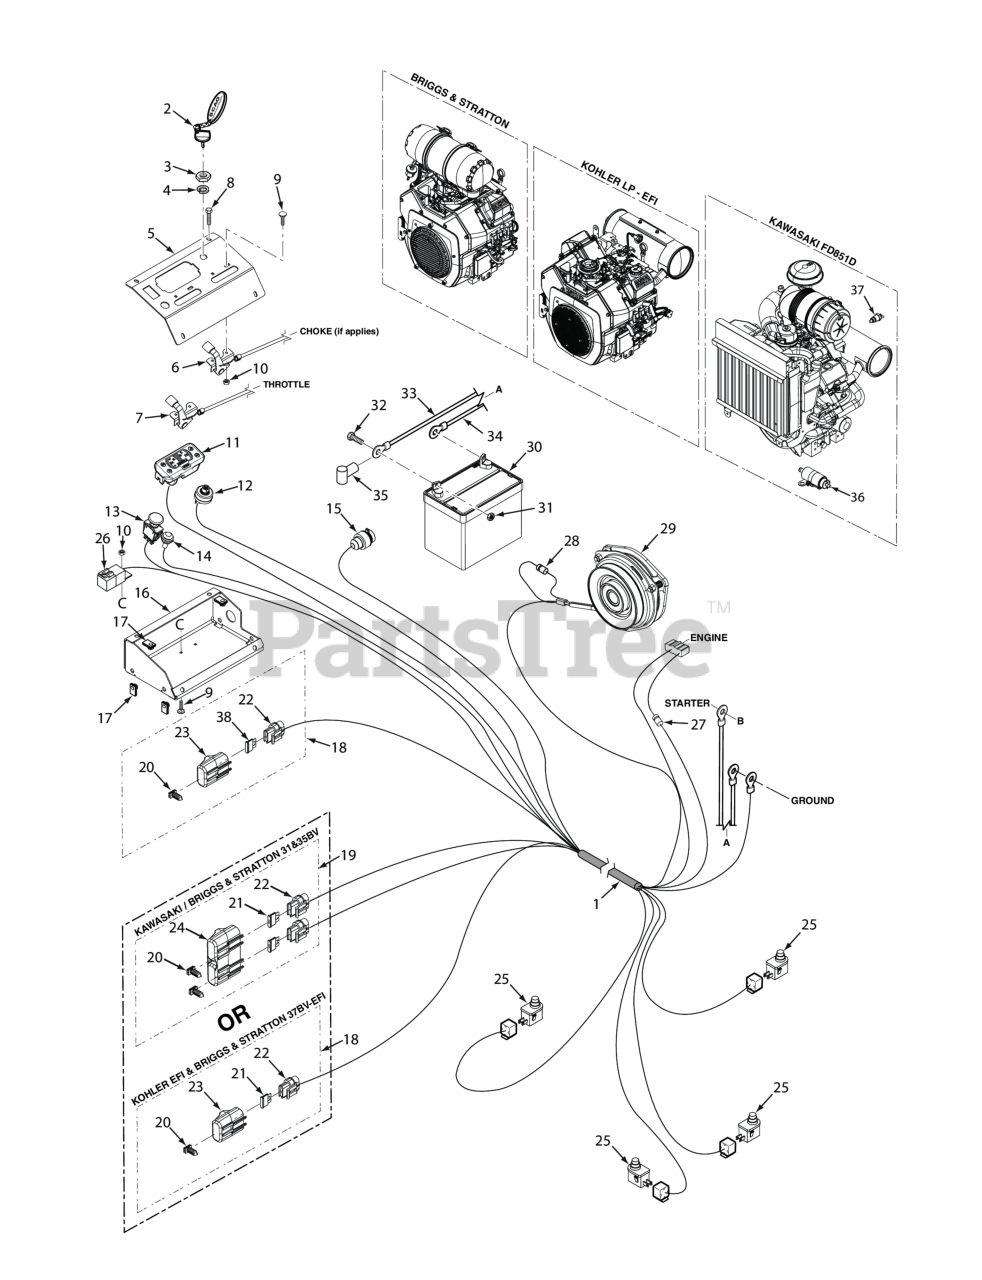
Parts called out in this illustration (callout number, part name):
1	Wire Harness, STTII-BV-EFI (Briggs & Stratton)
2	Key, Assembly w/Fob
3	Nut, 5/8-32 Special
4	LOCK WASHER, 5/8" INTERNAL TOOTH
5	Instrument Panel w/Decal
6	Control Cable (Kawasaki FX921 Throttle & Choke Cable)
7	Control Cable (Briggs & Stratton)
8	Bolt, Hex Head Serrated Flange 1/4-20 x 3/4"
9	Bolt, Carriage #10-24 x 1/2"
10	Nut, Elastic Stop #10-24
11	Tiger Eye, Cluster Gauge
12	KEY SWITCH(INCLUDES MOUNTING HARDWARE)
13	Switch, PTO - 10 Amp
14	Indicator Light, Glow Plugs (Includes Mounting Hardware)
15	Power Plug, 12V
16	Base, Instrument Panel
17	Bolt, Hex Head 3/8-16 x 1"
18	Single Fuse Assy., Excluding Fuse
19	Double Fuse Assy.
20	Clip, Fuse Holder
21	FUSE, 20 AMP BLADE TYPE AUTOMOTIVE
22	Fuse Holder Assembly
23	Cover, Sealed Single
24	Cover, Sealed Double
25	Switch, Interlock, Normally Open
26	Relay, 12V 40 AMP Standard
27	Decal, Forward Speed Selector
28	Diode, 600V 6 Amp
29	Electric Clutch w/Tag - GT-3.5 (FX850)
30	Battery, 350 CCA
31	Nut, 1/4 - 20 Hex
32	Bolt, Hex Head 1/4-20 x .5" Battery, (Not Available Through Scag)
33	Battery Cable, 50" Red w/Braid (35BV & 37BV-EFI) - Briggs & Stratton
34	Battery Cable, 27" Black (35BV & 37BV-EFI) - Briggs & Stratton
35	RUBBER BOOT
36	Battery, 350 CCA
37	Sender Unit, Water Temp. (Liquid Cooled Only)
38	Fuse, 5 Amp
